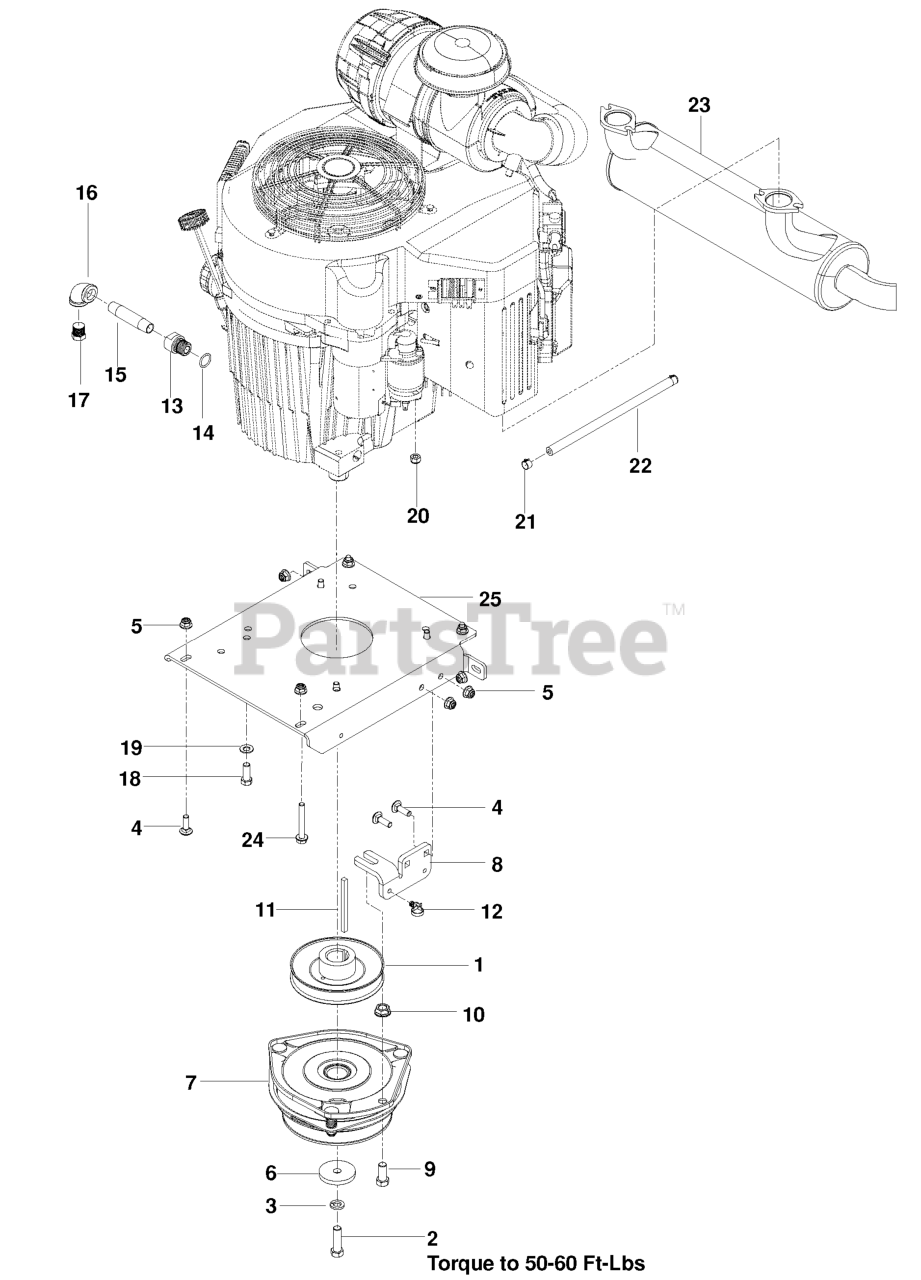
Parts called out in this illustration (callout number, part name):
1	PULLEY, ENGINE
2	HCS 7/16F X 1 1/2
3	WASHER 7/16 LOCK
4	RHSNB 5/16C X 1
5	5/16-18 NYLOC FLANGE NUT
6	BLADE WASHER
7	CLUTCH, GT3.5
8	STOP, CLUTCH, OGURA
9	HCS 7/16-14 X 1 GR 5 ZD
10	NUT 7/16C WHIZ
11	KEY, 1/4 SQ X 3.5
12	TIE WRAP, 8-3/8", W/CLIP
13	ADAPTER, OIL DRAIN
15	PIPE NIPPLE 3/8 X 3
16	90 DEG.ELBOW 3/8NPT
17	PLUG, DRAIN 3/8 NPTF
18	HCS 3/8-16X1.GRD.5.ZD
19	WASHER, 3/8 DISC SPRING SPEC
20	NUT M8-1.25 TOP NYL GR10 ZD
21	HOSE CLAMP
22	GAS LINE 10"
23	MUFFLER.26HP.KAW.FX651V-730V
24	HHFS 5/16-18 X 2.25 GD 5
25	PLATE.ENGINE.BLACK
